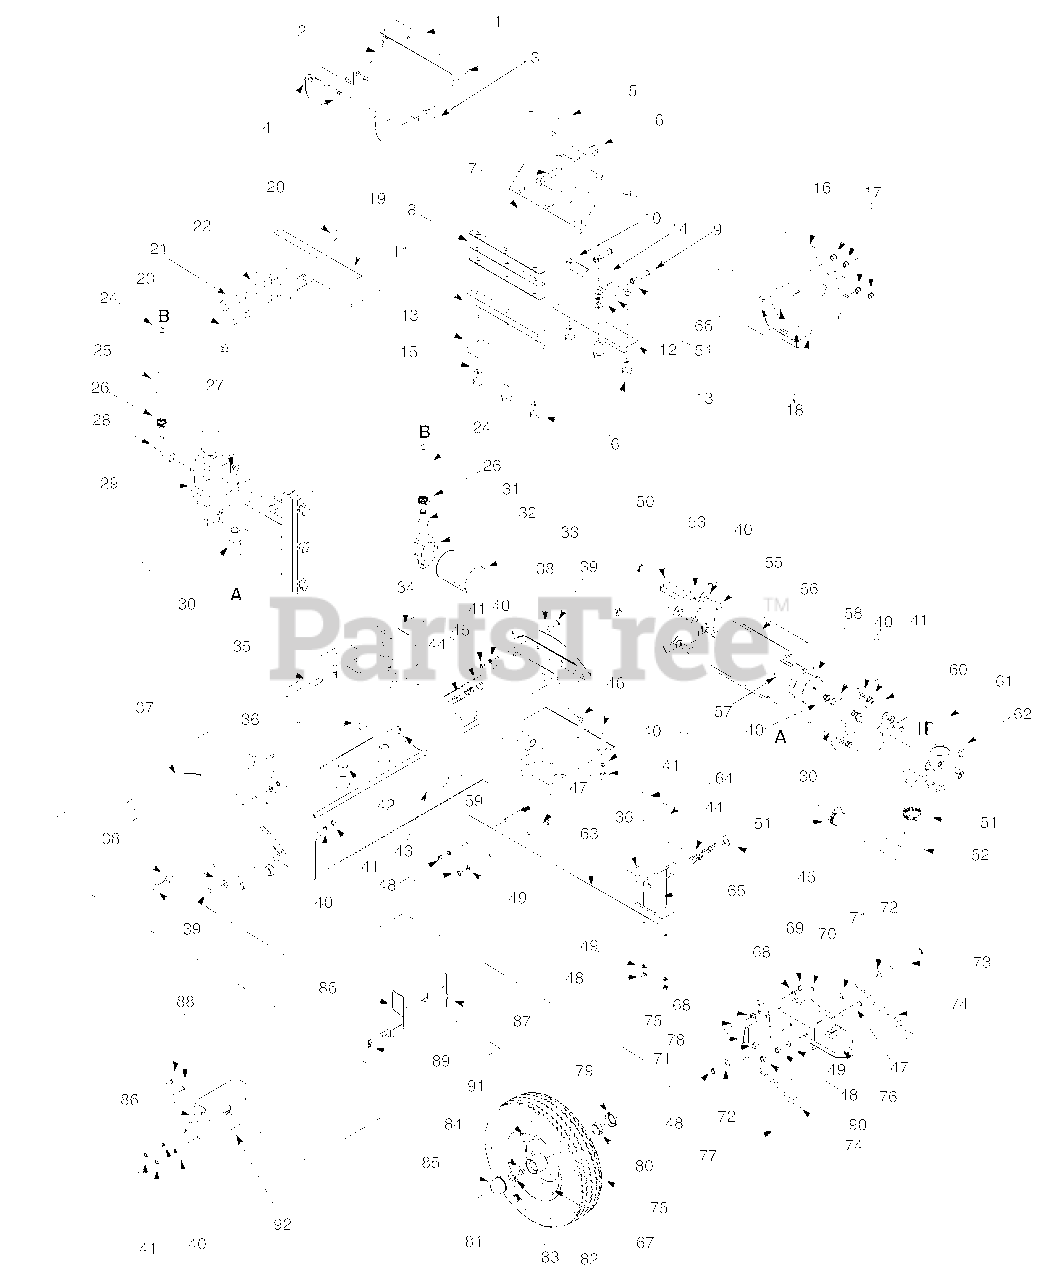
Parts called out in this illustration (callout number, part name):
4	Flanged Lock Nut, 3/8-16
6	Lock Nut, 1/2-20
7	Hex Head Screw, 1/2-20 x 2.75
10	Spacer
12	Flat Washer, .531 ID x .94 OD
15	Lock Washer, 1/2
18	Hex Cap Screw, 3/8-16 2.5
21	Clevis Pin
24	Return Hose, 3/4 x 44 Lg
25	Hose Guard
26	Hose Clamp
27	Tube Adapter
28	Return Elbow
30	High Pressure Hydraulic Hose
32	Filter Head
33	Oil Filter
34	Cotter Pin
35	Hinge Pin
36	Locking Rod
39	Hex Cap Screw, 5/16-24 x .75
40	Lock Washer, 5/16
41	Hex Nut, 5/16-24
42	Pipe Plug
46	Hex Cap Screw, 5/16-24 x 1.75
47	Hex Screw, 3/8-16 x 3
48	Hex Nut, 3/8-16
49	Lock Washer, 3/8
50	Hex Screw, 5/16-24 x 4
51	Hose Clamp
52	Suction Hose
54	Adjustable Gib, 5/8 x 5/8 x 2
55	Hex Cap Screw, 5/16-24
56	Coupling Shield
58	Flex Coupling
59	Flat Washer, .63 x .93 x .060
62	Gear Pump (11 GPM)
64	Hex Screw, 3/8-16 x 4.0
67	Rim Assembly
68	Flat Washer, .406" ID x .75" OD
69	Hex Lock Nut, 3/8-16
70	Clevis Pin
72	Flat Washer, 3/8" ID x .87" OD
73	Hex Bolt, 3/8-16 x 4.25"
74	Chain
75	Tire, 16 x 4.8
76	Hitch Coupler
79	Bearing Seal
80	Tapered Bearing
81	Wheel Assembly
82	Slotted Nut, 3/4-16
83	Cotter Pin
84	Flat Washer, .760 ID x .500 OD
86	Tail Light Assembly
89	Speed Clip
90	Hex Jam Nut, 3/8-16
91	Valve
